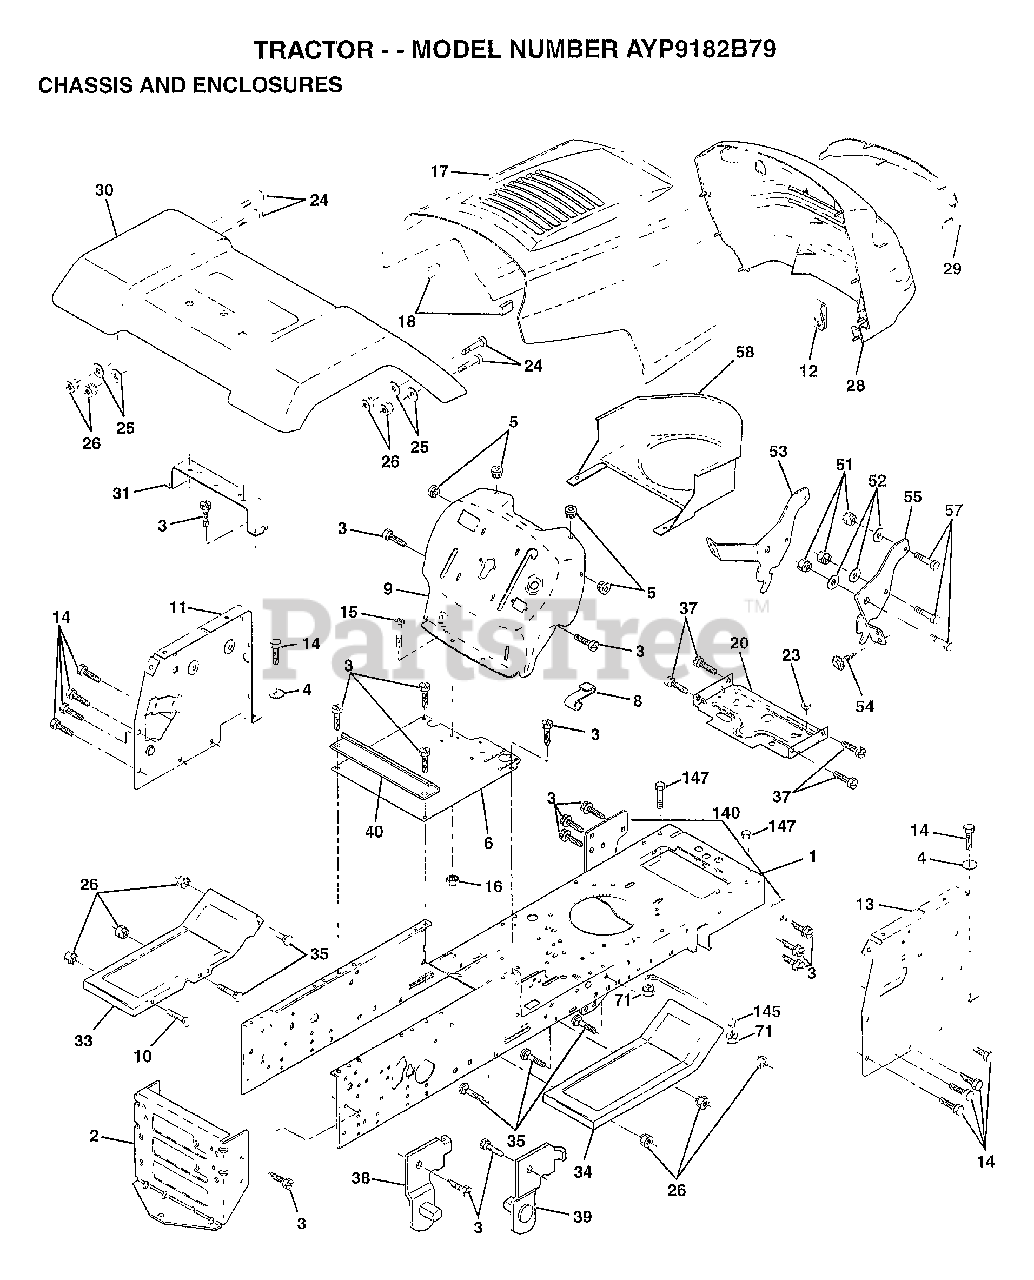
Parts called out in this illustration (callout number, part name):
1	CHASSIS ASM
3	SCREW
4	WASHER
5	BUMPER-HOOD/DASH
6	SADDLE
8	"CLIP,INSULATOR"
9	DASH.SILKSCREENED
11	"PANEL-DASH,LH"
12	CLIP.TINNERMAN
14	SCREW LT
15	SCREW
20	"PLATE-MTG,BATT/FU"
24	BOLT
25	WASHER
26	NUT
28	GRILL.BLK
29	LENS GRILLE
30	FENDER LT
31	BRACKET SUPT FEND
33	FOOTREST LH
34	FOOTREST RH
35	BOLT
37	SCREW LT
38	BRACKET ASM LH
39	BRACKET ASM RH
40	SPACER FENDER LT
51	NUT
52	WASHER
53	BRACKET.GRILLE.LH
55	BRACKET.GRILLE.RH
58	DUCT.AIR.B&S.18HP
140	BRKT SUSPENSION
145	"ROD POVOT,CHASSIS"
147	BOLT LT
